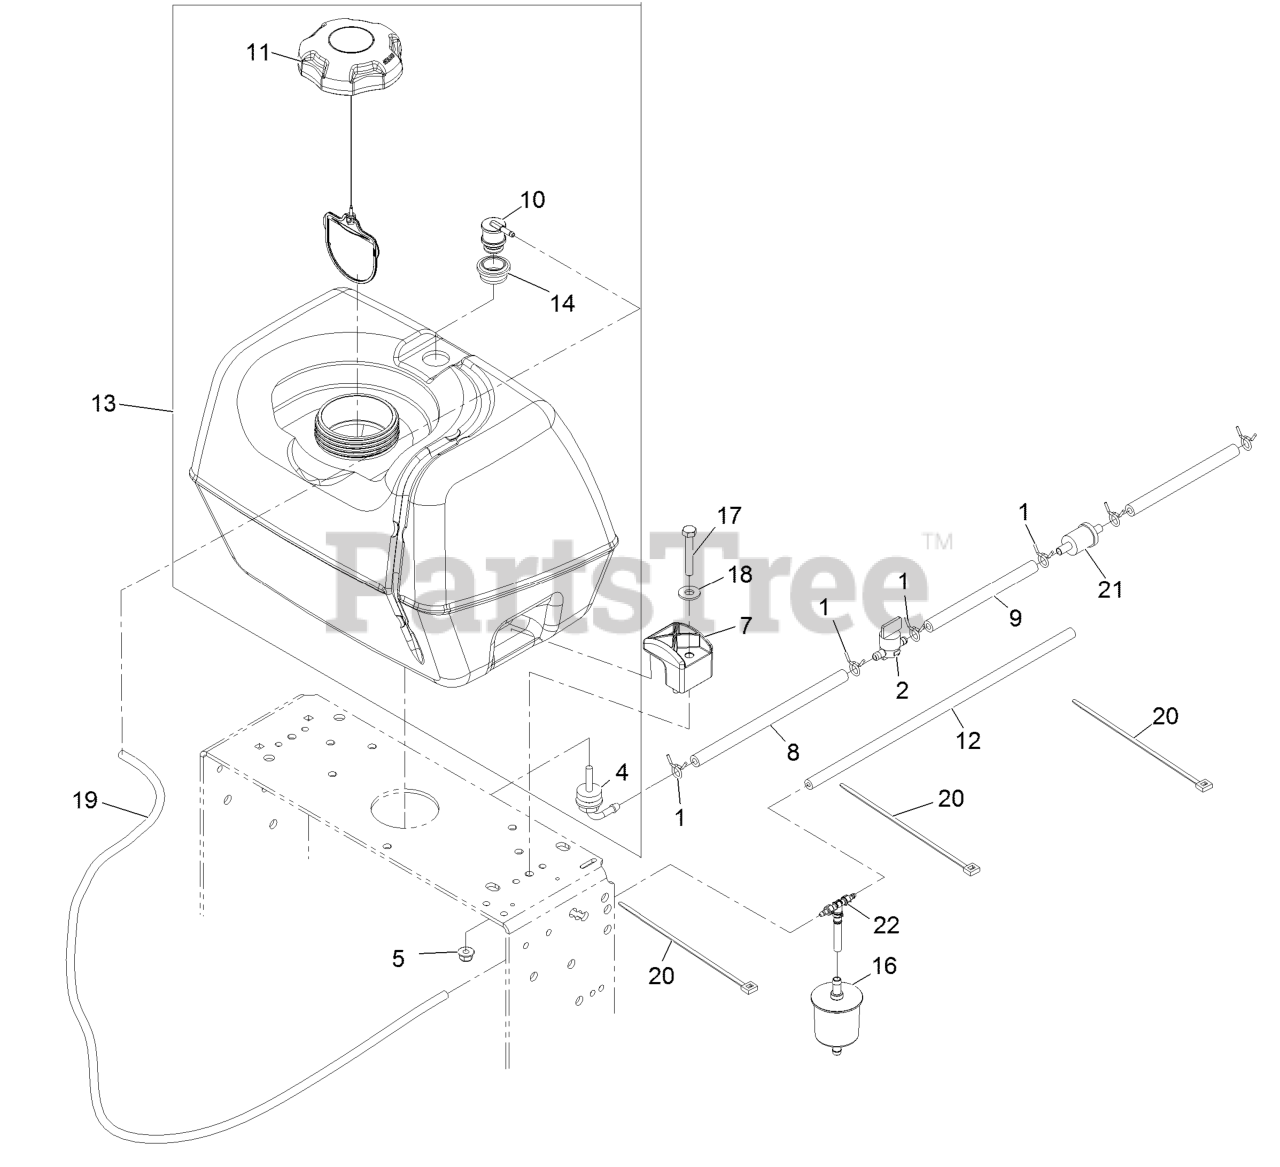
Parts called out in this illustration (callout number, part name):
1	CLAMP-HOSE
2	VALVE-FUEL
4	FITTING-FUEL, BULKHEAD
5	NUT-HF, NI
8	HOSE-FUEL
9	HOSE-FUEL
10	VALVE-VENT, FUEL
12	HOSE-FUEL
13	ASM, FUEL TANK
14	GROMMET
16	FILTER-FUEL
17	SCREW-HH
18	WASHER-FLAT
19	HOSE-EMISSIONS
20	TIE-PLASTIC
21	Pn 41019-1055 Filter W/6in Fuel Line
22	TEE AND CHECK
